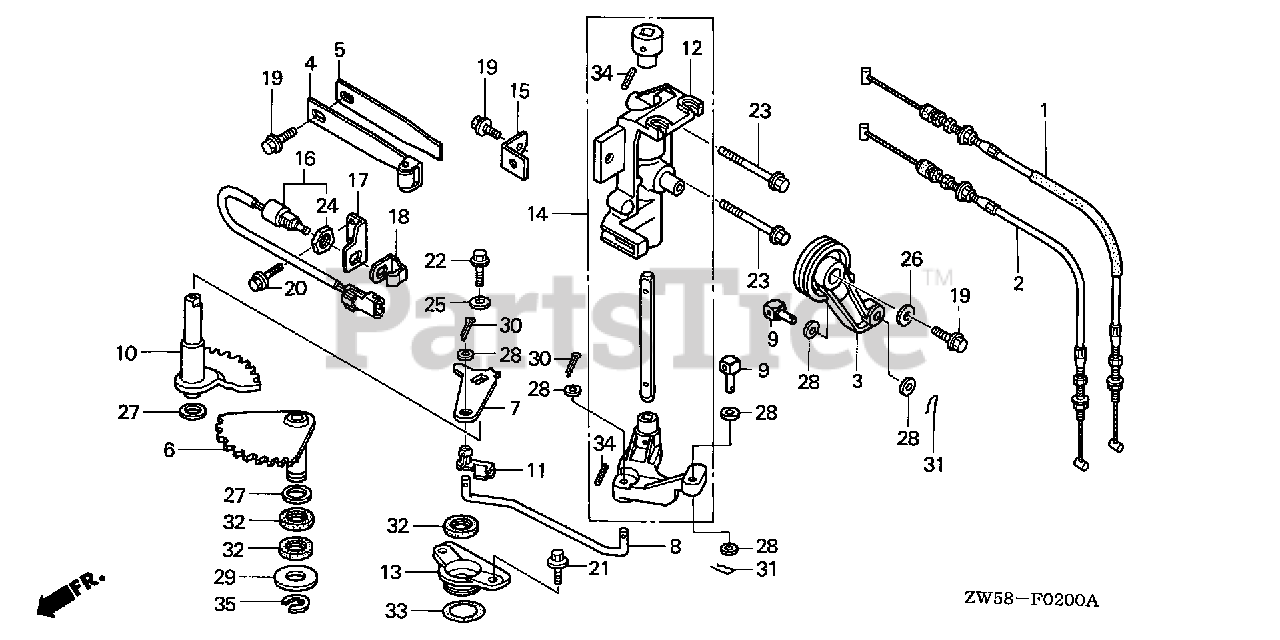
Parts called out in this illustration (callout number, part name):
1	CABLE A, THROTTLE
2	CABLE B, THROTTLE
3	ARM, THROTTLE
4	SPRING, CLICK
5	SPRING, CLICK ASSIST
6	SHAFT, SHIFT (A)
7	ARM, SHIFT
9	PIVOT, SHIFT
10	SHAFT, SHIFT (B)
11	BUSH, SHAFT
12	BRACKET, SHIFT LINK
13	HOLDER, SEAL
14	LINK, SHIFT
14	LINK, SHIFT *NH8* (DARK GRAY)
15	BRACKET, CLIP (D)
16	SWITCH ASSY., NEUTRAL
17	BRACKET, NEUTRAL SWITCH
18	PLATE, NEUTRAL SWITCH
19	BOLT, FLANGE (6X12) (CT200)
20	BOLT, FLANGE (6X14) (CT200)
21	BOLT, FLANGE (6X11)
22	BOLT, FLANGE (6X12)
23	BOLT, FLANGE (6X42)
24	NUT, HEX. (20MM)
25	WASHER (6MM)
26	WASHER, PLAIN (6MM)
27	WASHER, SHIFT SHAFT
28	WASHER, PLAIN (6MM)
30	PIN, SPLIT (2.0)
31	PIN, LOCK SPECIAL (6MM)
32	OIL SEAL (14X26X6)
33	O-RING (26.9X2.4) (NOK)
34	PIN, SPRING (3X18)
35	E-RING (12MM)
